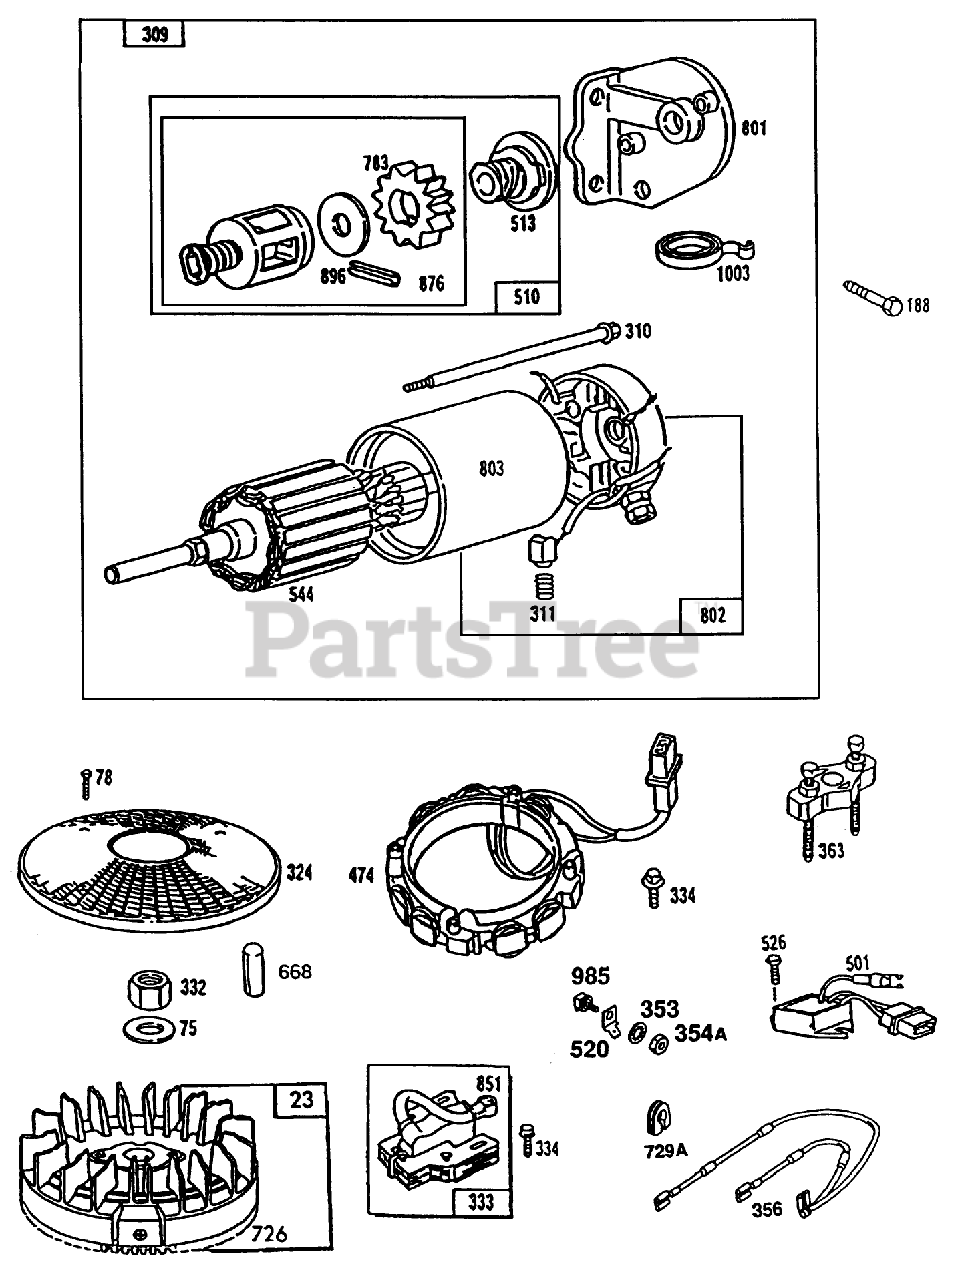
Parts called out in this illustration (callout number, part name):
75	BRIGGS-805007
78	BRIGGS-805447
188	BRIGGS-805247
310	BRIGGS-94169
311	Brush Assembly
324	BRIGGS-494439
332	BRIGGS-805021
334	BRIGGS-805407
356	BRIGGS-493792
363	BRIGGS-19203
513	BRIGGS-398003
526	BRIGGS-805448
668	BRIGGS-807688
803	BRIGGS-399172
876	BRIGGS-490467
896	BRIGGS 94288
985	Insulator
1003	BRIGGS-805025
